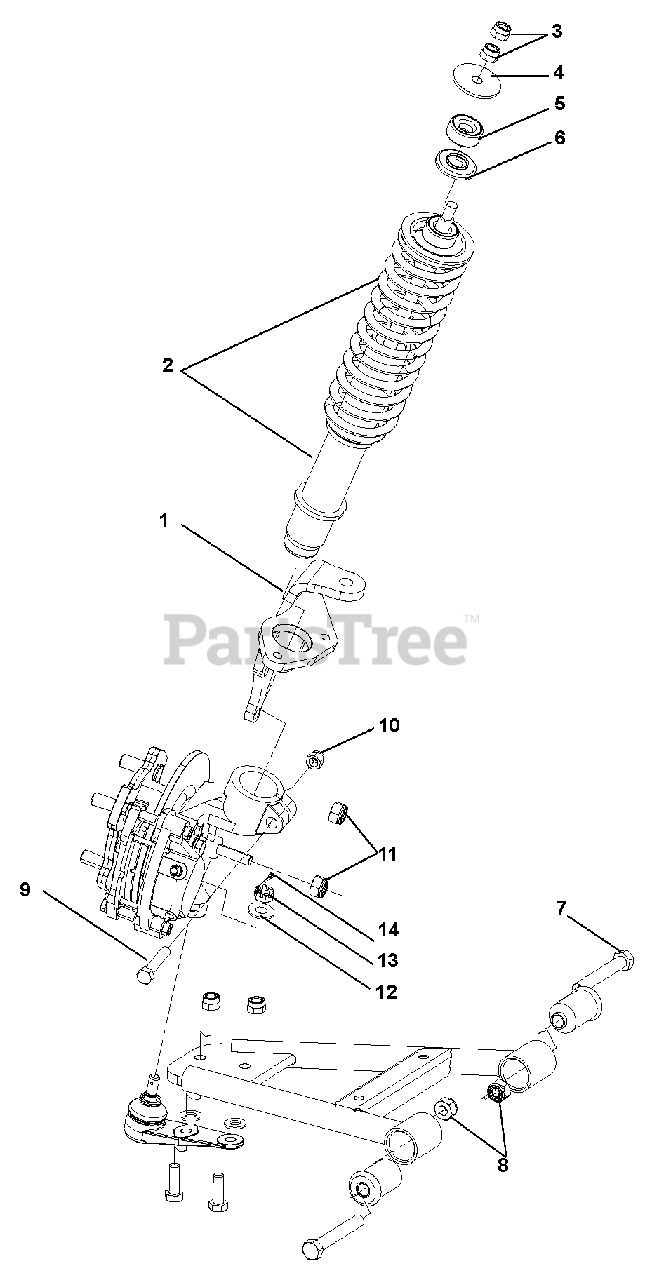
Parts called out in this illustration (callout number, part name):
1	STEERING BRACKET RIGHT
2	STRUT/COIL SPRING ASSEMBLY
3	NUT, HEX JAM M10 X 1.25 6MTHK YLW
4	WASHER, FLAT 1.92OD X .413ID X .118T
5	GROMMET, RUBBER MOUNT
6	WASHER, STRUT MOUNT
7	HHCS M12 X 1.75 X 80 GR8.8 PLT
8	NUT, LOCK NYLON M12 X 1.75 PLT
9	BOLT, HEX .38-16 X 2.00 GR8
10	NUT, LOCK NYLON .38-16 YWZC
11	NUT, HEX NYLOCK M10 X 1.5 PLT
12	WASHER, FLAT STEEL .438 X 1.00 X .083 YWZC
13	NUT, HEX SLOTTED M10 X 1.25 YWZC
14	PIN, COTTER .09 X 1 LONG
